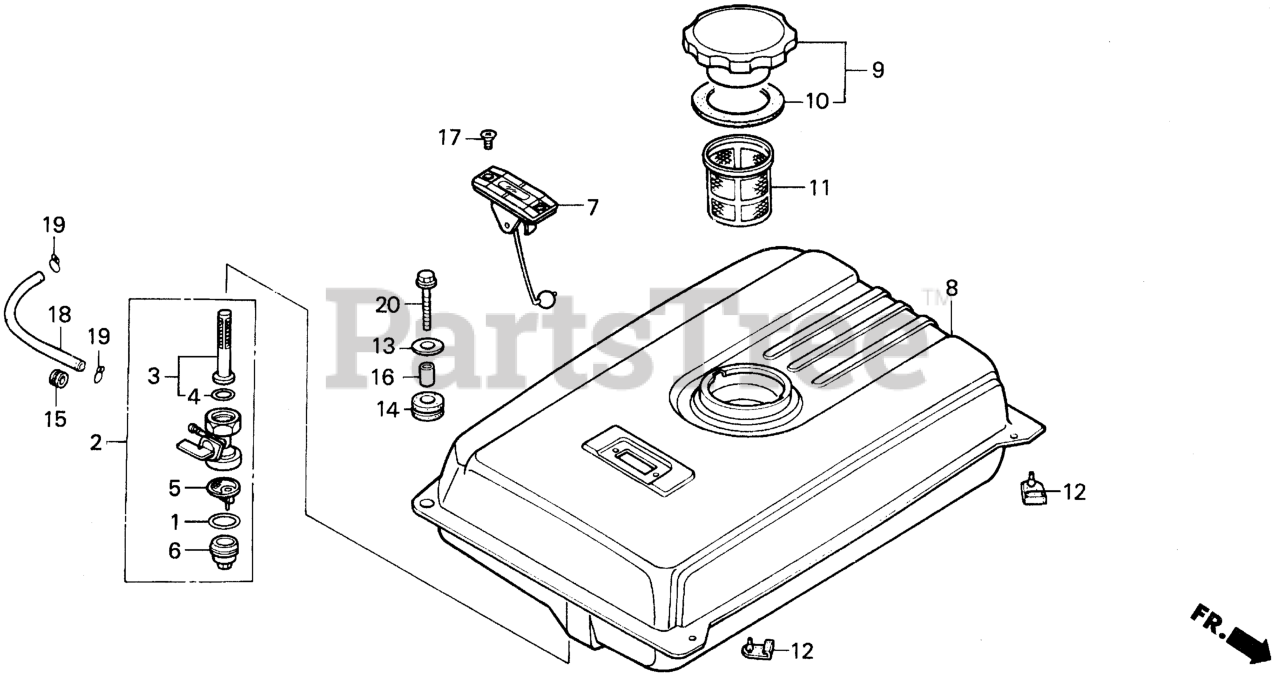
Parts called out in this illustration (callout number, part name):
1	GASKET, FUEL STRAINER CUP
2	PETCOCK ASSY.
3	SCREEN SET, FUEL STRAINER
4	O-RING (9.0X1.3)
5	FILTER, CUP
6	CUP, FUEL STRAINER
8	TANK, FUEL *R8* (BRIGHT RED)
9	CAP, FUEL FILLER
10	GASKET, FUEL FILLER CAP
11	FILTER, FUEL
12	RUBBER, TANK MOUNTING
13	WASHER, TANK CUSHION
14	CUSHION, TANK RUBBER
15	RUBBER, FUEL (9X15X10)
16	COLLAR, TANK CUSHION
18	BULK HOSE, FUEL (4.5X3000) (Honda Code 5137104). (4.5X140)
19	CLIP, TUBE (B8)
20	BOLT, FLANGE (6X22)
20	BOLT, FLANGE (6X25)
